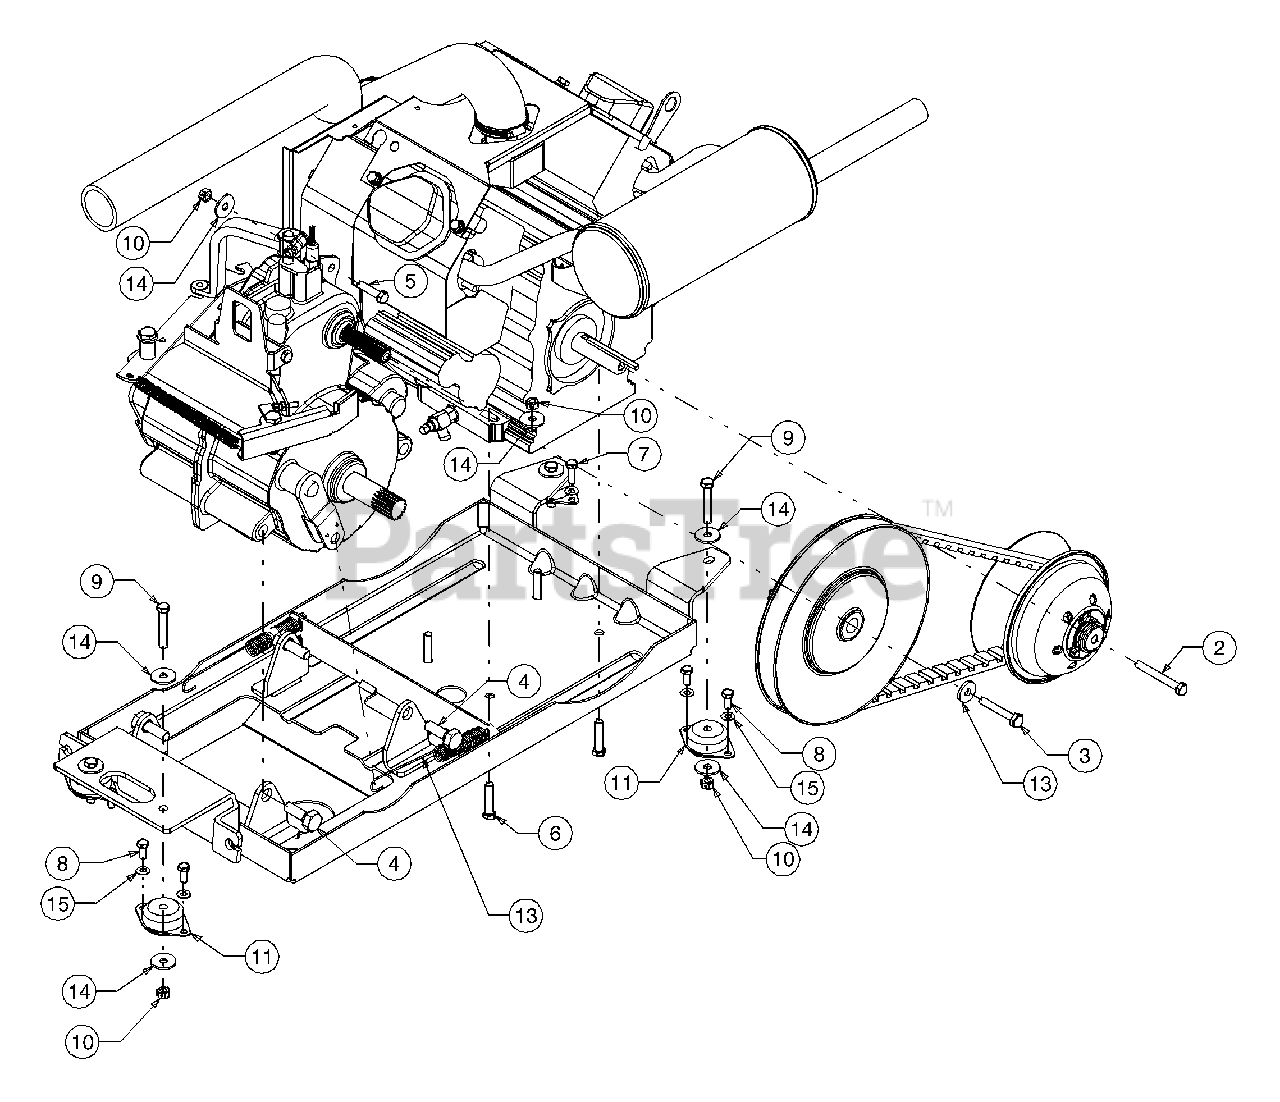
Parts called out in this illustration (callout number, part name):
2	Hex Screw, 3/8-24 x 3, Gr5
3	Hex Screw, M10-1.5 x 60mm, Gr8
4	Hex Screw, M16-2 x 40mm
5	Hex Screw, 3/8-16 x 1.5, Gr5
6	Hex Screw, 3/8-16 x 1.75, Gr5
7	Hex Screw, 5/16-18 x 1.0, Gr5
8	Hex Screw, 5/16-18 x .75, Gr5
9	Hex Screw, 3/8-16 x 2.25, Gr5
10	Nut, Hex Lock, 3/8-16
11	Mount, Isolator
13	Washer, Flat, .395 x 1.12 x .14
14	Washer, Flat, .411 x 1.25 x .10
15	Washer, Flat, .330 x .687 x .030
